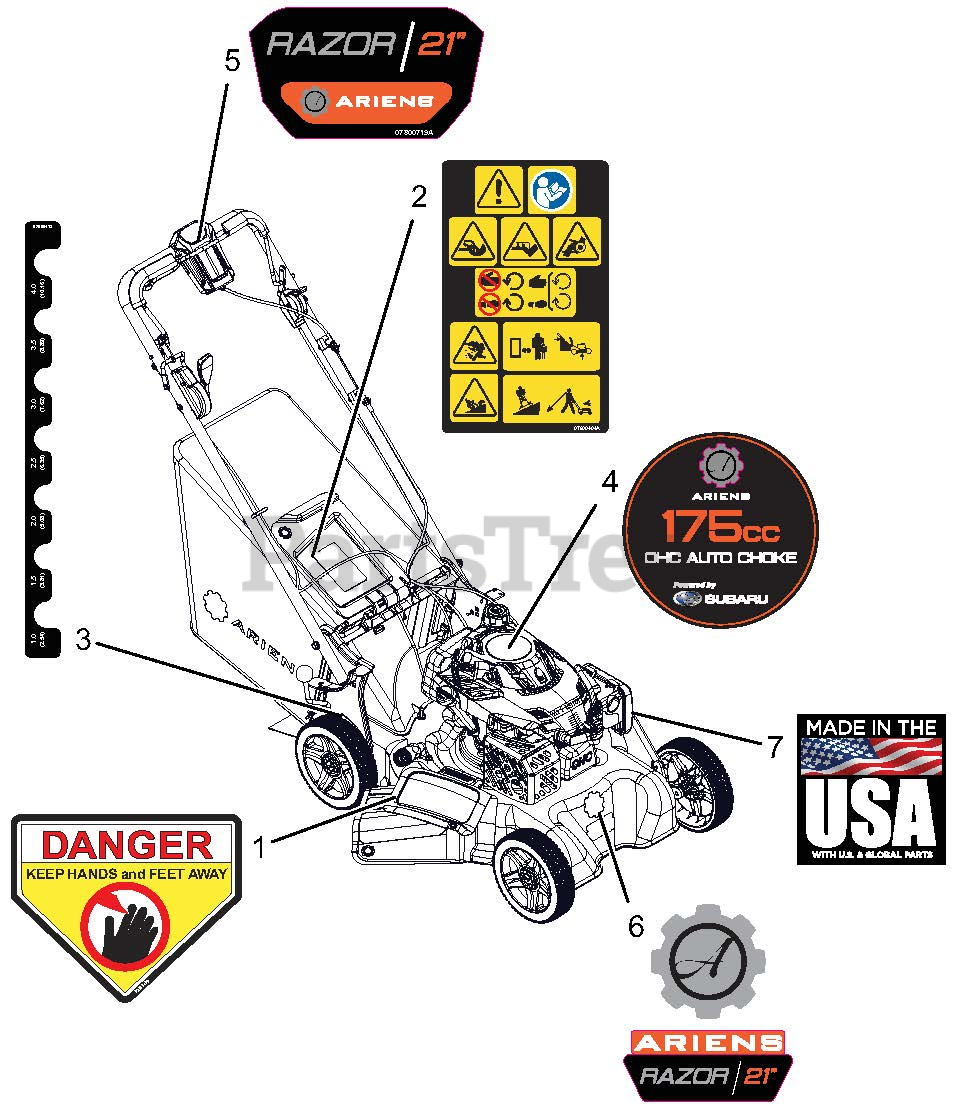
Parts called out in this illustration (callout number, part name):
1	DECAL, DANGER
2	DECAL,MAIN SAFETY_WAW LM
3	DECAL, HOC
4	DECAL-ENGINE STYLE-RAZOR
5	DECAL-CONTROL-RAZOR
6	DECAL-ARIENS RAZOR 21"
7	DECAL, MADE IN USA
